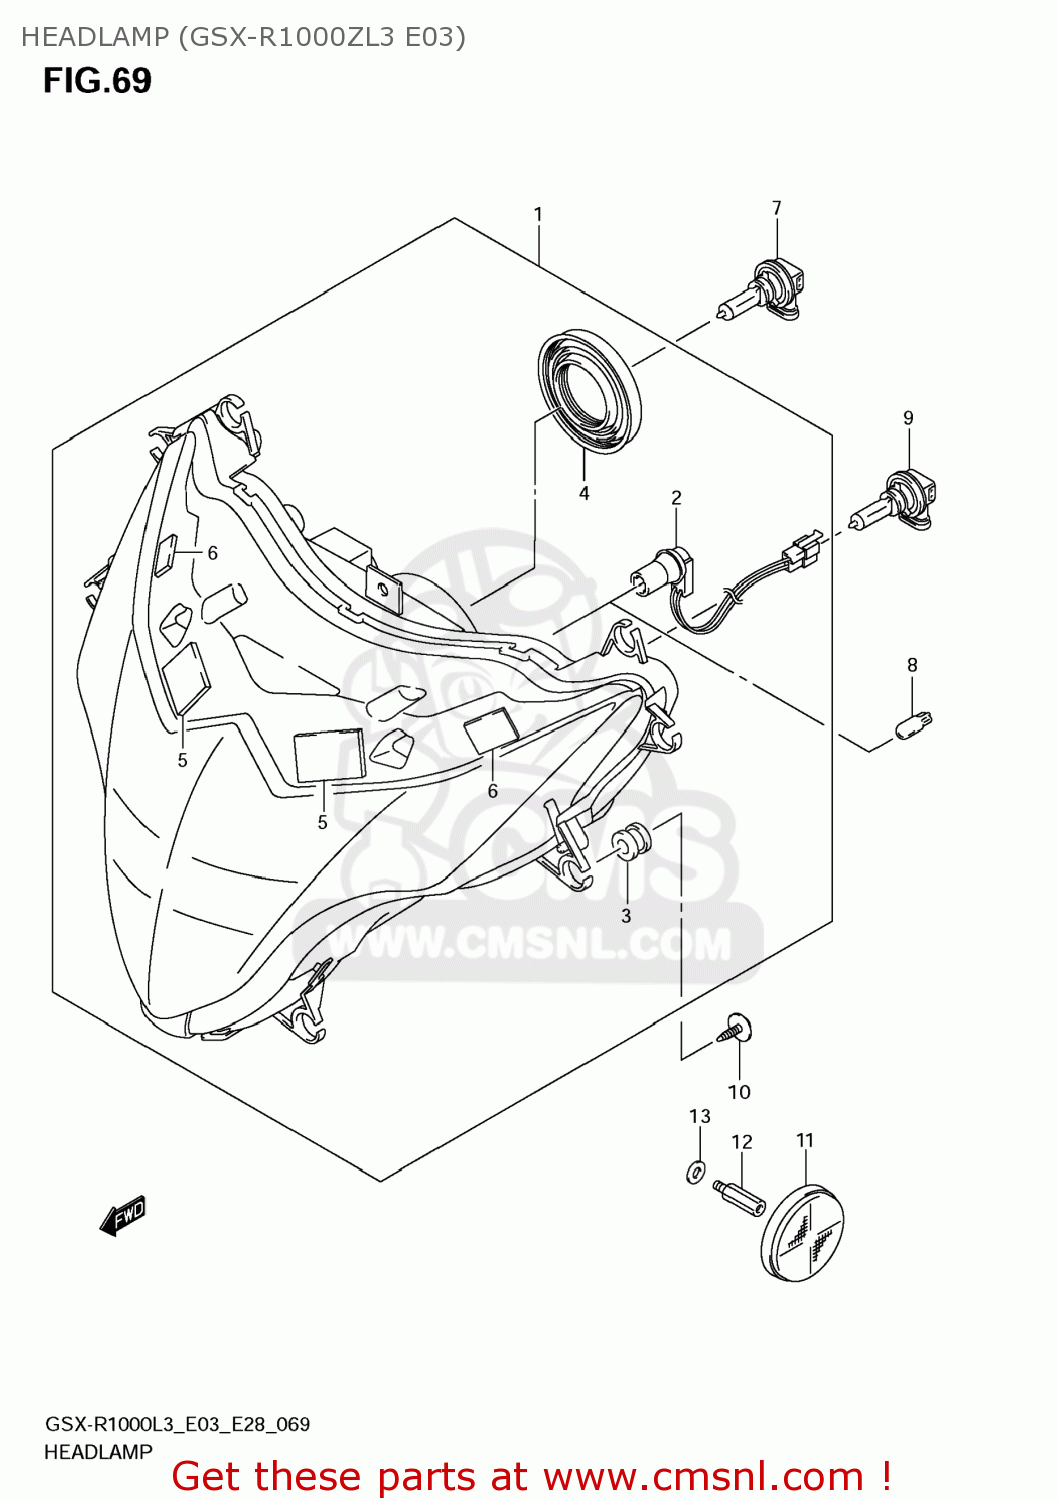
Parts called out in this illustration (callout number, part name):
1	HEADLAMP ASSY
2	CORD ASSY
3	CUSHION
4	COVER,SOCKET
5	FASTENER
6	FASTENER,COWLING
7	BULB(12V55W,H11)
8	BULB(12V5W)
9	BULB(12V65W,H9)
10	SCREW(5X15)
11	REFLEX REFLECTOR ASSY,FR SIDE
12	BOLT
13	WASHER(8.5X18X1)
